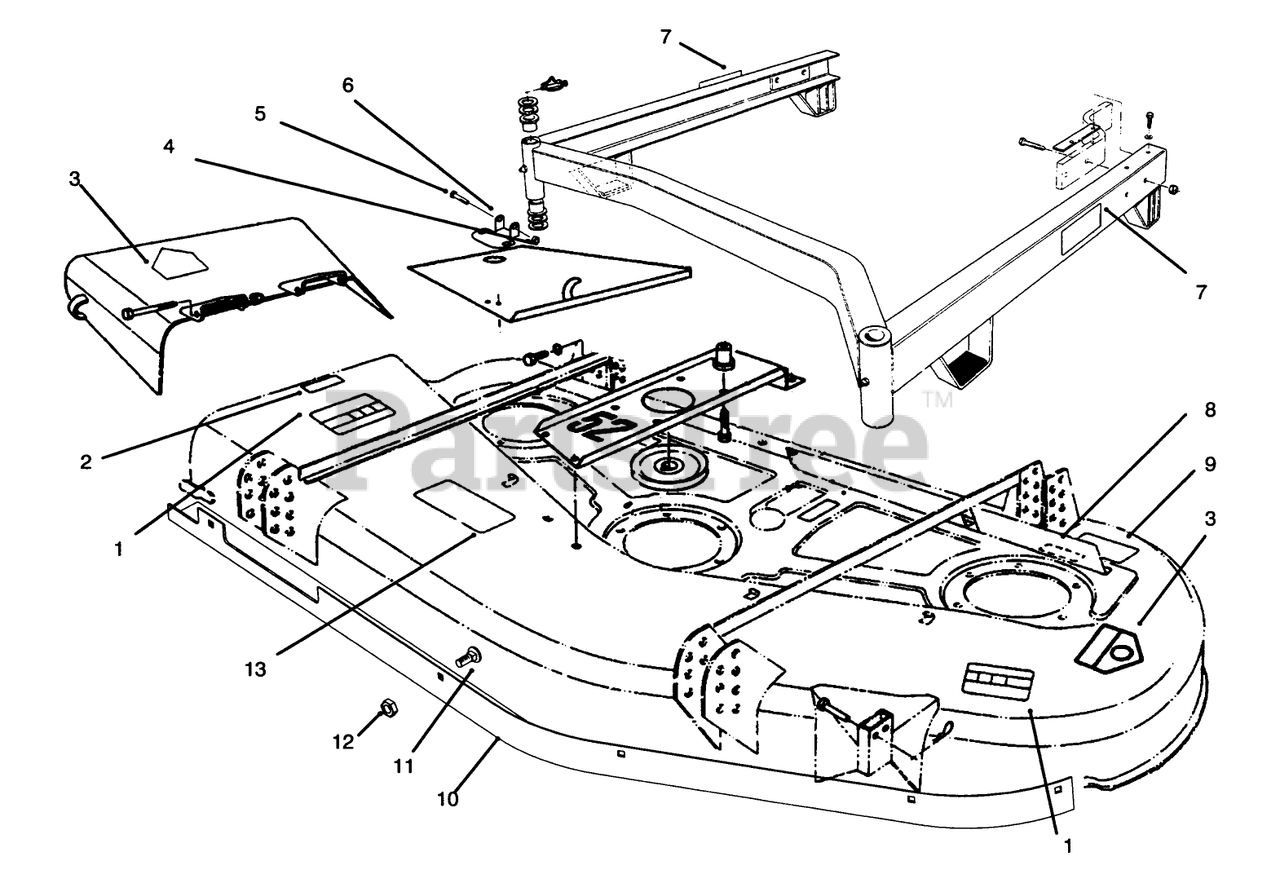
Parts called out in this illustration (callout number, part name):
1	DECAL-DANGER
2	DECAL - WARNING
3	DECAL-DANGER
4	NUT-LOCK, NI
5	SCREW-HH
6	RETAINER-LATCH
7	DECAL-HOC
8	DECAL-DANGER
9	DECAL-TORQUE, BLADE BOLT
10	Baffle
11	SCREW-CARR
12	NUT-LOCK, NI
13	DECAL - WARNING
